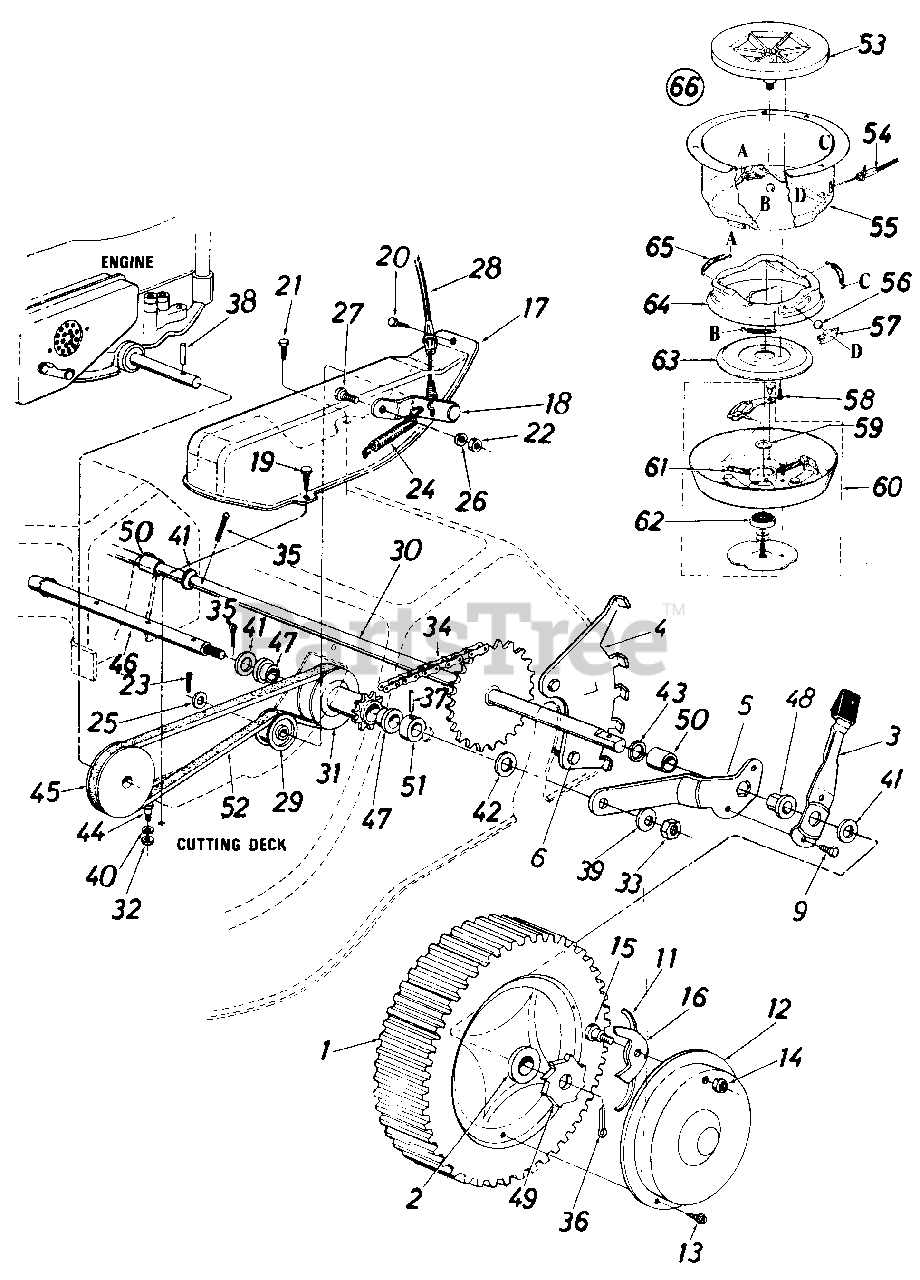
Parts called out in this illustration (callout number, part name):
1	Wheel Ass'y. Comp. 8.0 x 1 .75
2	Flange Brg.-1/2" I.D.
3	Spring Lever w/Knob
4	Index Plate Ass'y.-L.H.
5	Pivot Brkt.-L.H.
6	Hex Wash. Hd. Tap Scr. 1/4 x .62"
9	Hex B-Tap Scr. 1/4 x .38"
11	Nylon Spring
12	Hub Cap
13	Pan Hd. Tap Scr. #12 x .50"
14	Hex Ins. L-Nut 1/4-20 Thd.
15	Shld. Bolt .342" Dia. x .268
16	Pawl
17	Belt Cover
18	Idler Bracket Ass'y.
19	Hex Wash. Hd. Self-Tap Scr. 1/4-20 x .50" Lg.
20	Hex Drilling Scr. #10 x .50"
21	Hex TT-Tap Scr. 1/4-20 x .75"
22	Hex Nut 1/4-20 Thd.
23	Cotter Pin 1/8" Dia. x 1.00"*
24	Extension Spring .33" O.D. x 1.12" Lg.
25	Fl-Wash. .531" I.D. x .930" O.D.
26	L-Wash. 1/4" I.D.
27	Shld. Bolt .375" Dia. x .181
28	Clutch Cable-50"
29	Flat Idler-Plastic
30	Rear Shaft Ass'y.
31	Pulley w/9 Tooth Sprocket Ass'y.
32	Hex Nut 5/16-18 Thd.
33	Hex Jam Nut 3/8-16 Thd.
34	#48 Chain 1/2" Pitch x 31 Links
35	Cotter Pin 3/32" Dia. x 1.00"
36	Cotter Pin 1/8" Dia. x 1.00"
37	Spring Pin Spir. 3/16" Dia. x 1.00" Lg.
38	Spring Pin Spir. 3/16" Dia. x 1.50" Lg.
39	Bell-Wash. .400" I.D. x .88"
40	L-Wash. 5/16" I.D.
41	Fl-Wash. .531" I.D. x .930"
42	Bell-Wash. .400" I.D. x 1.13"
43	Fl-Wash. .510" I.D. x 1.0" O.D.
44	Shld. Bolt .437" Dia. x .350"
45	Engine Pulley
46	Pulley Shaft-10.0" Lg.
47	Flange Brg. .506" I.D. Plastic
48	Hex Flange Brg. .506" I.D. Plastic
49	Ratchet
50	Spacer .765" I.D. x .89" O.D. x.960" Lg.
51	Spacer .505" I.D. x .88" O.D. x.44" Lg.
52	"V"-Belt
53	Fan Adapter
54	Clutch Cable-46"
55	Clutch Housing
56	Steel Ball .50" Dia.
57	Ball Block
58	Hex TT-Tap L-Scr. 1/4-20 x .75" Lg.
59	Fl-Wash. .69" I.D. x 1.06"
60	Clutch Blade Housing Ass'y.
61	Compression Spring .35" O.D. x 2.00" Lg.
62	Ball Brg. .669" I.D. x 1.574" O.D. x .47
63	Clutching Cone
64	Brake Cup Cone
65	Extension Spring .35" O.D. x 1.75" Lg.
66	Blade Brake/Clutch Ass'y. Comp.
